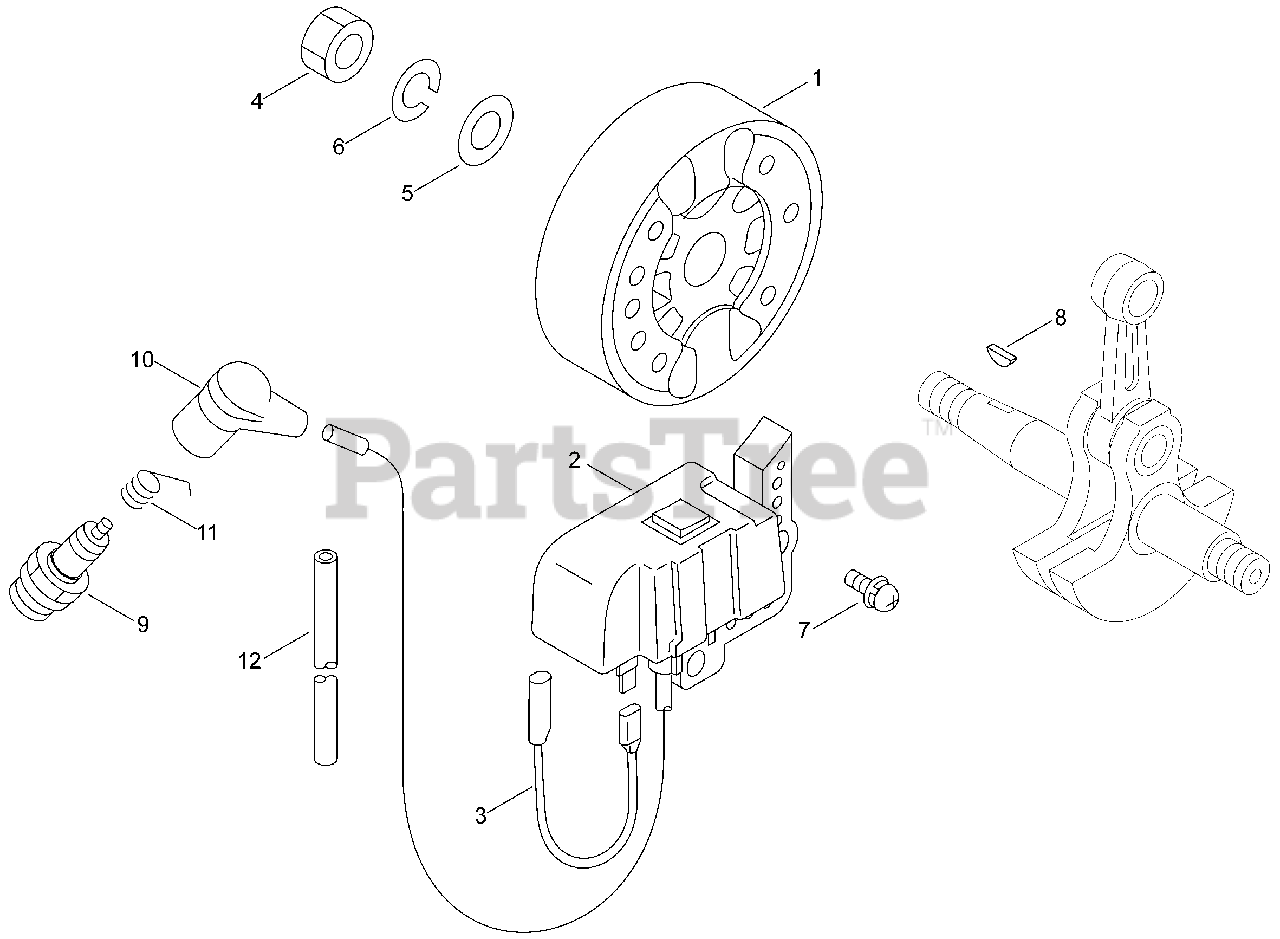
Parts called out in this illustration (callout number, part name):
1	FLYWHEEL
2	COIL, IGNITION
3	LEAD - IGNITION
5	WASHER 10
6	WASHER, SPRING 10
7	SCREW 5×18
8	KEY, WOODRUFF 3×14
9	SPARK PLUG - BPM7Y
10	CAP, SPARK PLUG
11	TERMINAL, SPARK PLUG
12	TUBE, IGNITION COIL 6×8×340
